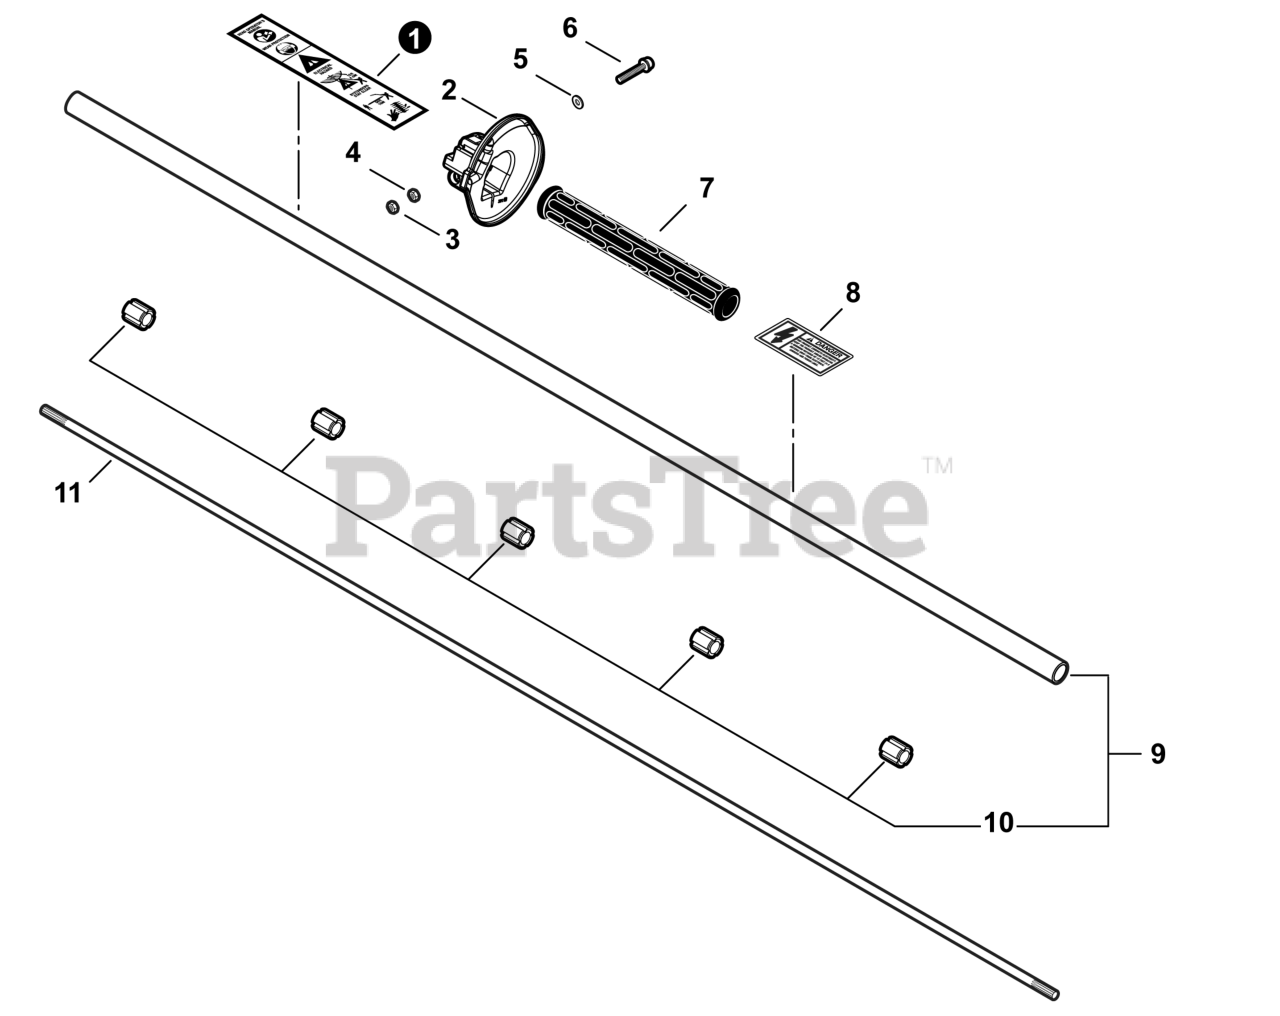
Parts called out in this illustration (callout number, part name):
1	LABEL - CAUTION
2	GUARD, HAND
3	NUT, LOCK M5
5	WASHER 5.5×12×0.8
6	SCREW - 5×35
7	GRIP, FRONT
8	LABEL - HIGH VOLTAGE
9	MAIN PIPE ASSY
10	BUSHING
11	MAINSHAFT
